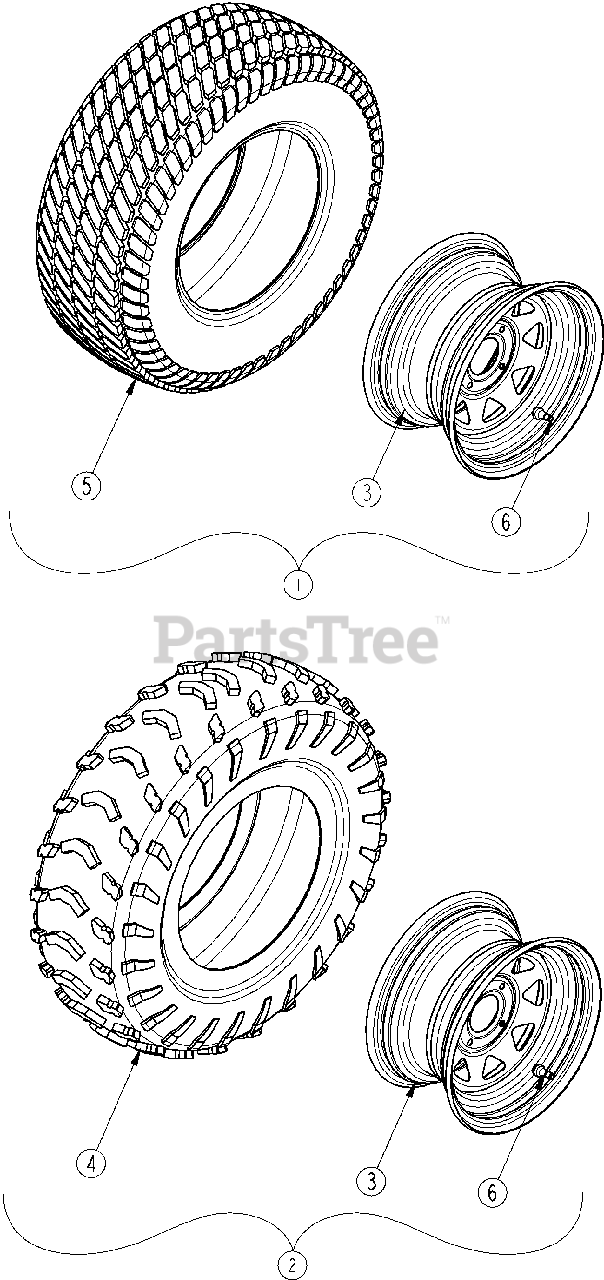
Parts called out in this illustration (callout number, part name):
1	TIRE/RIM FRONT TURF 23-8.5-12
2	AT TIRE/RIM, GRAY RIGHT FRONT
3	AT TIRE/RIM, BLACK RIGHT FRONT
4	AT TIRE/RIM, GRAY LEFT FRONT
5	AT TIRE/RIM, BLACK LEFT FRONT
6	RIM, 12X7 4-4 BOLT GRAY
